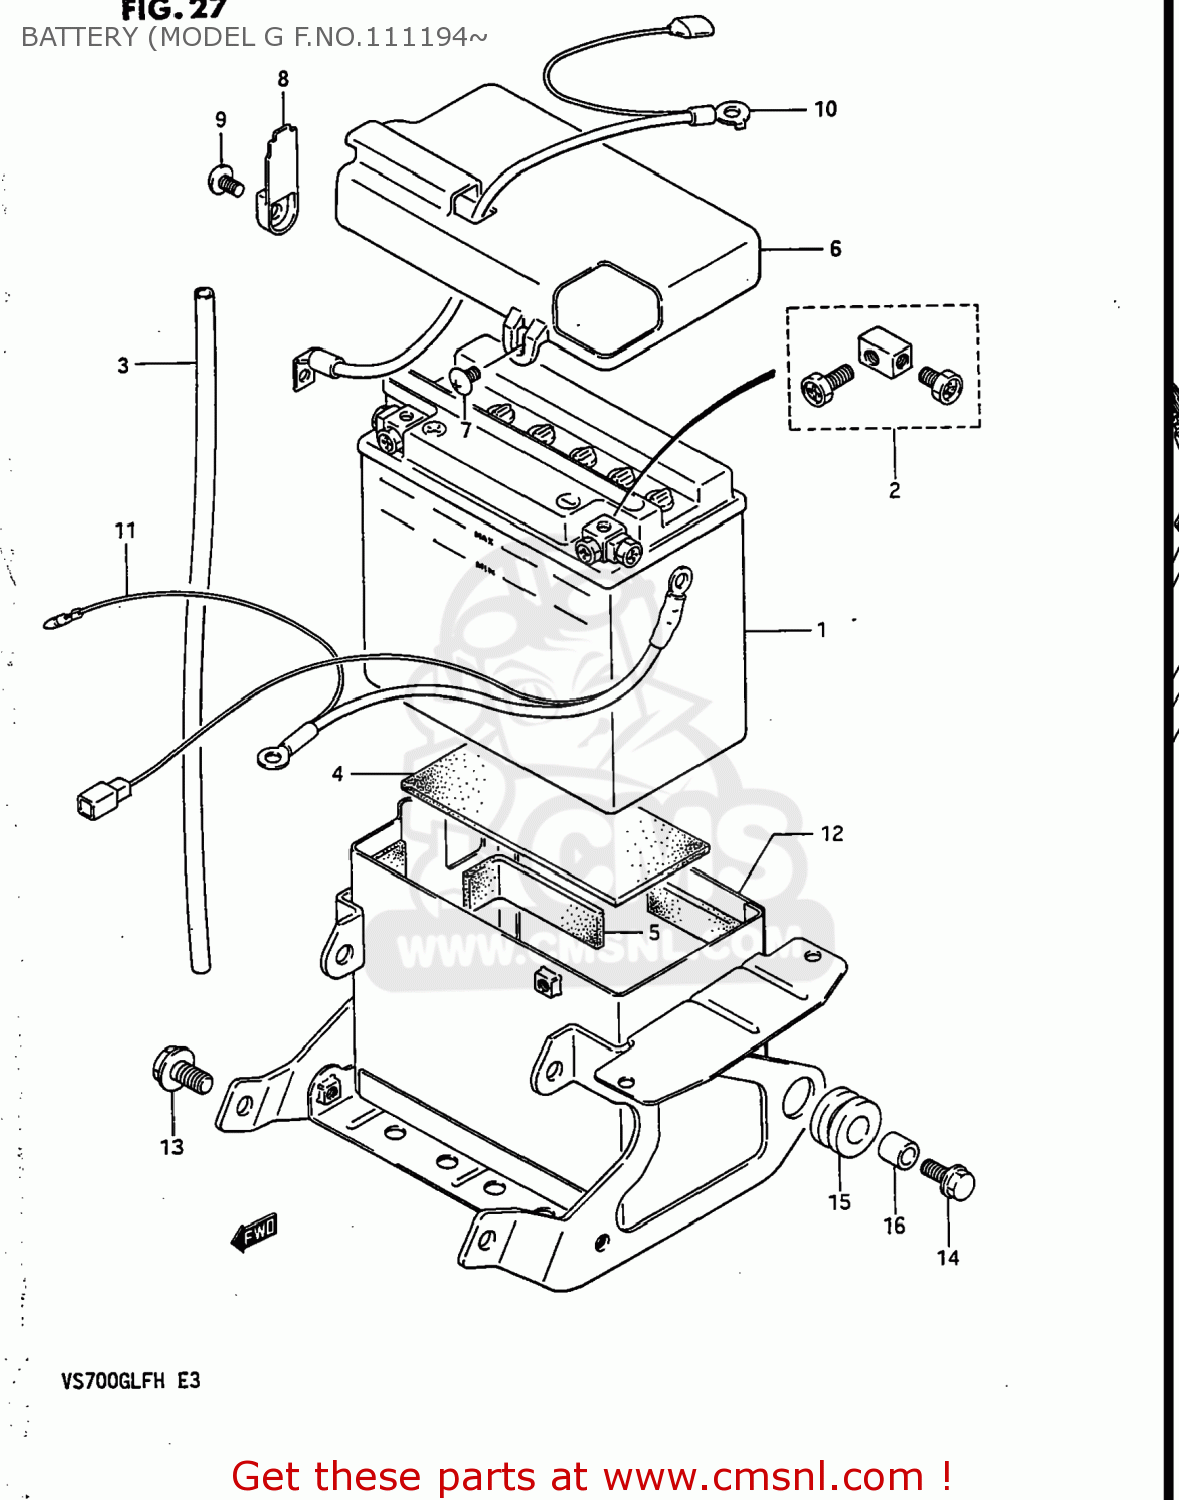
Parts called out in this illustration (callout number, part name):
1	BATTERY ASSEMBLY (12V)
2	BOLT SET,BATTERY TERMINAL
3	HOSE,BATTERY EXHAUST
4	PROTECTOR(170X95X3.0)
5	PROTECTOR(20X90)X2
6	COVER,BATTERY UPR
7	SCREW
8	COVER,BATTERY TERMINAL
9	SCREW
10	WIRE,BATTERY PLUS LEAD
11	WIRE,BATTERY MINUS LEAD
12	HOLDER,BATTERY
13	BOLT
14	BOLT
15	CUSHION
16	SPACER (8.8X12X11)
